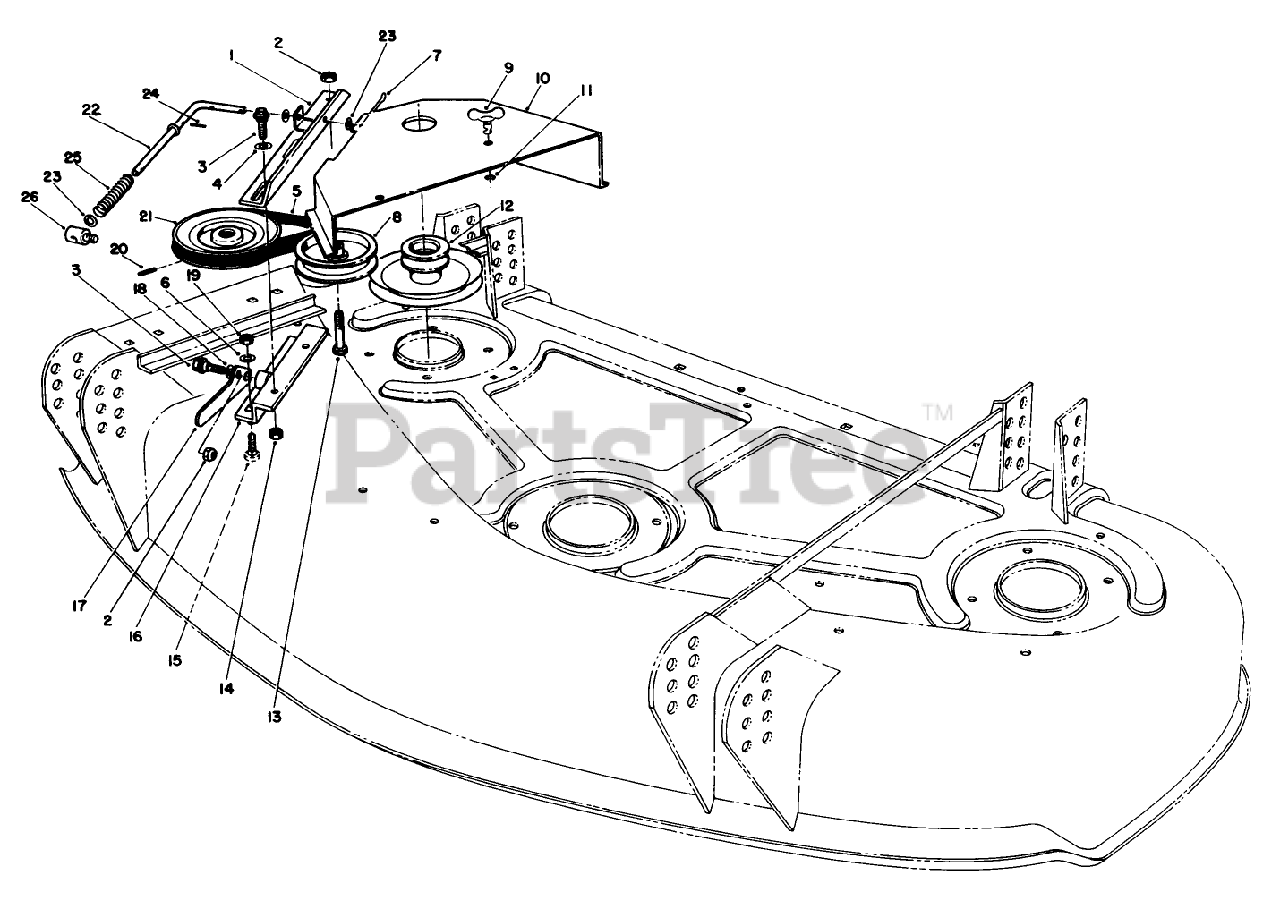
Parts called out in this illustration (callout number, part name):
1	Slide ldler
2	NUT-LOCK, NI
3	SCREW-SHOULDER
4	WASHER-THRUST
5	V-BELT
6	Washer
7	PIN-COTTER
8	PULLEY-IDLER
9	STUD-HEAD, WING
10	Cover-Deck
11	RING-SNAP
12	DECK PULLEY WA
12	PULLEY
13	SCREW-HH
14	NUT-LOCK, NI
15	SCREW-CARR
16	Bracket-Idler
17	Lever-Idler
18	WASHER-SPRING
19	NUT-KEPS
20	PIN-ROLL, SLOTTED
21	Pulley-Gear Box
22	Rod-Idler
23	WASHER-FLAT
24	PIN-ROLL
25	COMPRESSION SPRING
26	BAGGER TRUNNION
